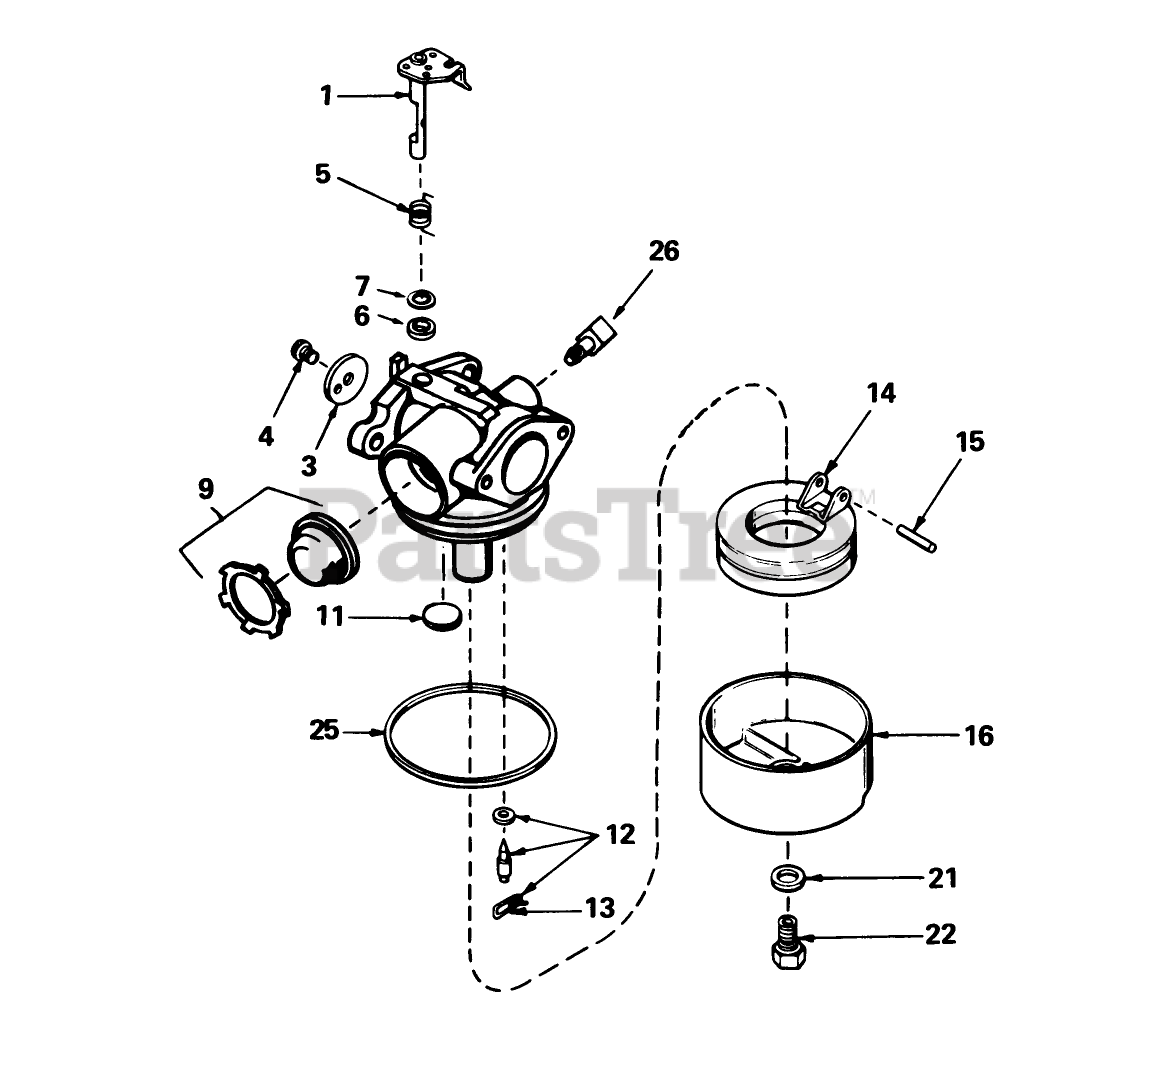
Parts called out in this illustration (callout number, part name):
1	Throttle Shaft and Lever ASM
3	Throttle-Shutter
4	Screw-Shutter
5	Spring-Return, Throttle
6	Seal-Dust
7	Washer-Seal, Dust
9	Primer Assy.
11	Plug-Welch, Atmospheric Vent
12	Inlet Needle, Seat Clip Assy. (Incl. No. 13)
13	Clip-Spring
14	Float
15	Shaft-Float
16	Bowl Float
21	Gasket-Bowl
22	Nut-Float Bowl
25	O Ring-Bowl, Float
26	Fitting-Fuel
